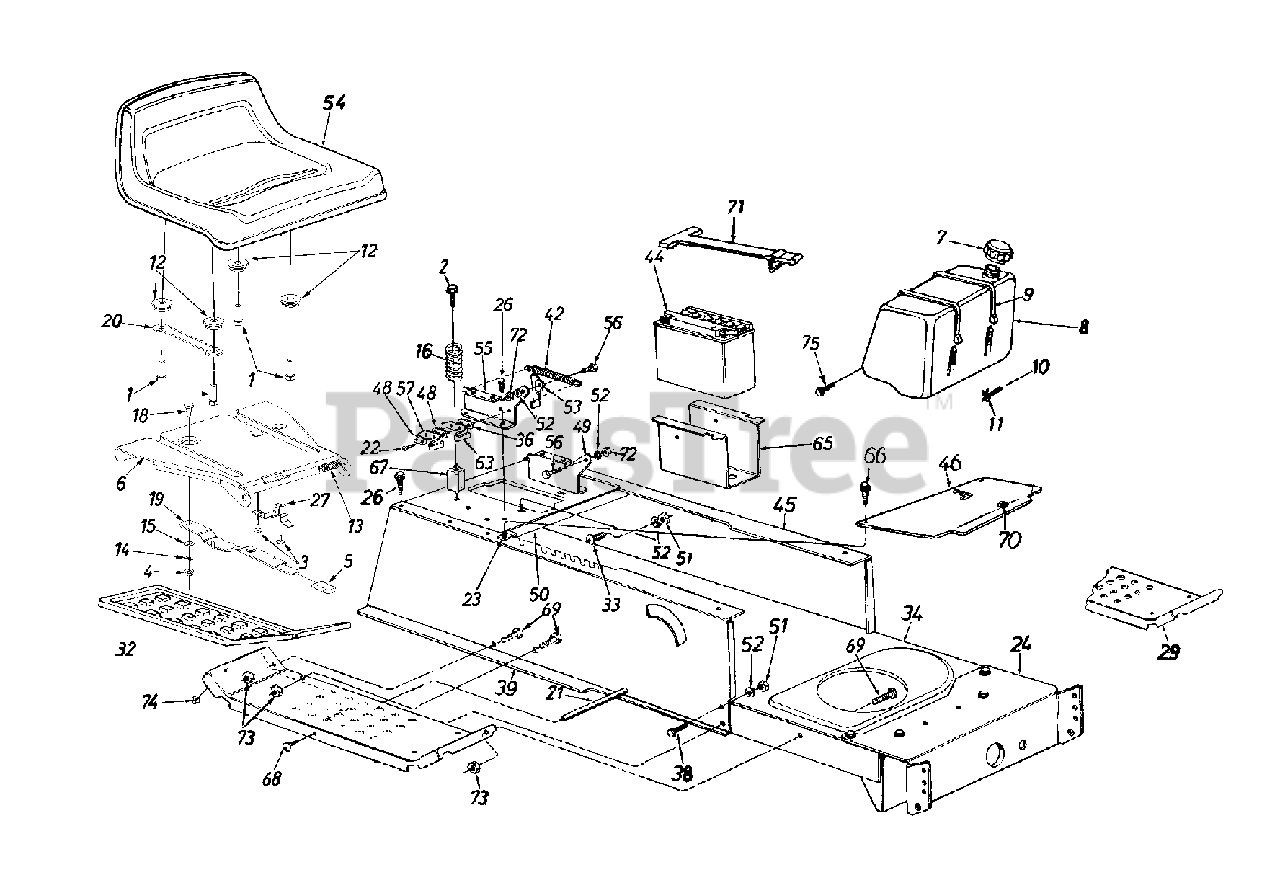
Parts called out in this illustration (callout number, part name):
1	Shoulder Screw 3/8-16 x .5
2	Hex Washer Tap Scr. 5/16-18 x 3.25" Lg.
3	Hx Scr. B-Tap Wash. #10-16: .38 Lg.
4	Lock Nut 1/4-20
9	Tie Strap
10	Fuel Line
13	Compression Spring
14	Wash. Spring .265 x .562 x .025
15	Fl. Wash..344 ID x .62 OD x .03
16	Compression Spring
18	Shldr. Scr. .340 x .285 - 1/4-20
20	Seat Selector
21	Running Board Rod
22	Hex AB-Tap Scr. #8 x .50"
23	Speed Nut #102
26	Hex Washer AB-Tap Scr. 5/16 x .75" Lg.
33	Truss Mach. Scr. 5/16-18 x .75" Lg.
36	Insulator Boss Plate
38	Hex Bolt 5/16-18 x .75" Lg."
44	12-V Battery
52	L-Wash. 5/16" I.D.
53	Seat Lift Brkt.
54	Seat
56	Shld. Bolt .437" Dia. x .268"
57	Spring Switch
63	Safety Switch (Seat)
66	Truss Mach. B-Tap Scr. #10 x .5" Lg.
67	Spring Spacer
68	Pan Hd. Scr. 5/16-18 x .75" Lg.
69	Hex Bolt 5/16-18 x .75" Lg.
70	Snap Bushing
71	Battery Retainer Strap
72	Hex Nut 5/16-18 Thd. (Gr. 5)
73	Hex Sems Nut 5/16-18 Thd.
74	Hex Sems Nut 1/4-20 Thd.
75	Hex Screw 12-24 x .62
